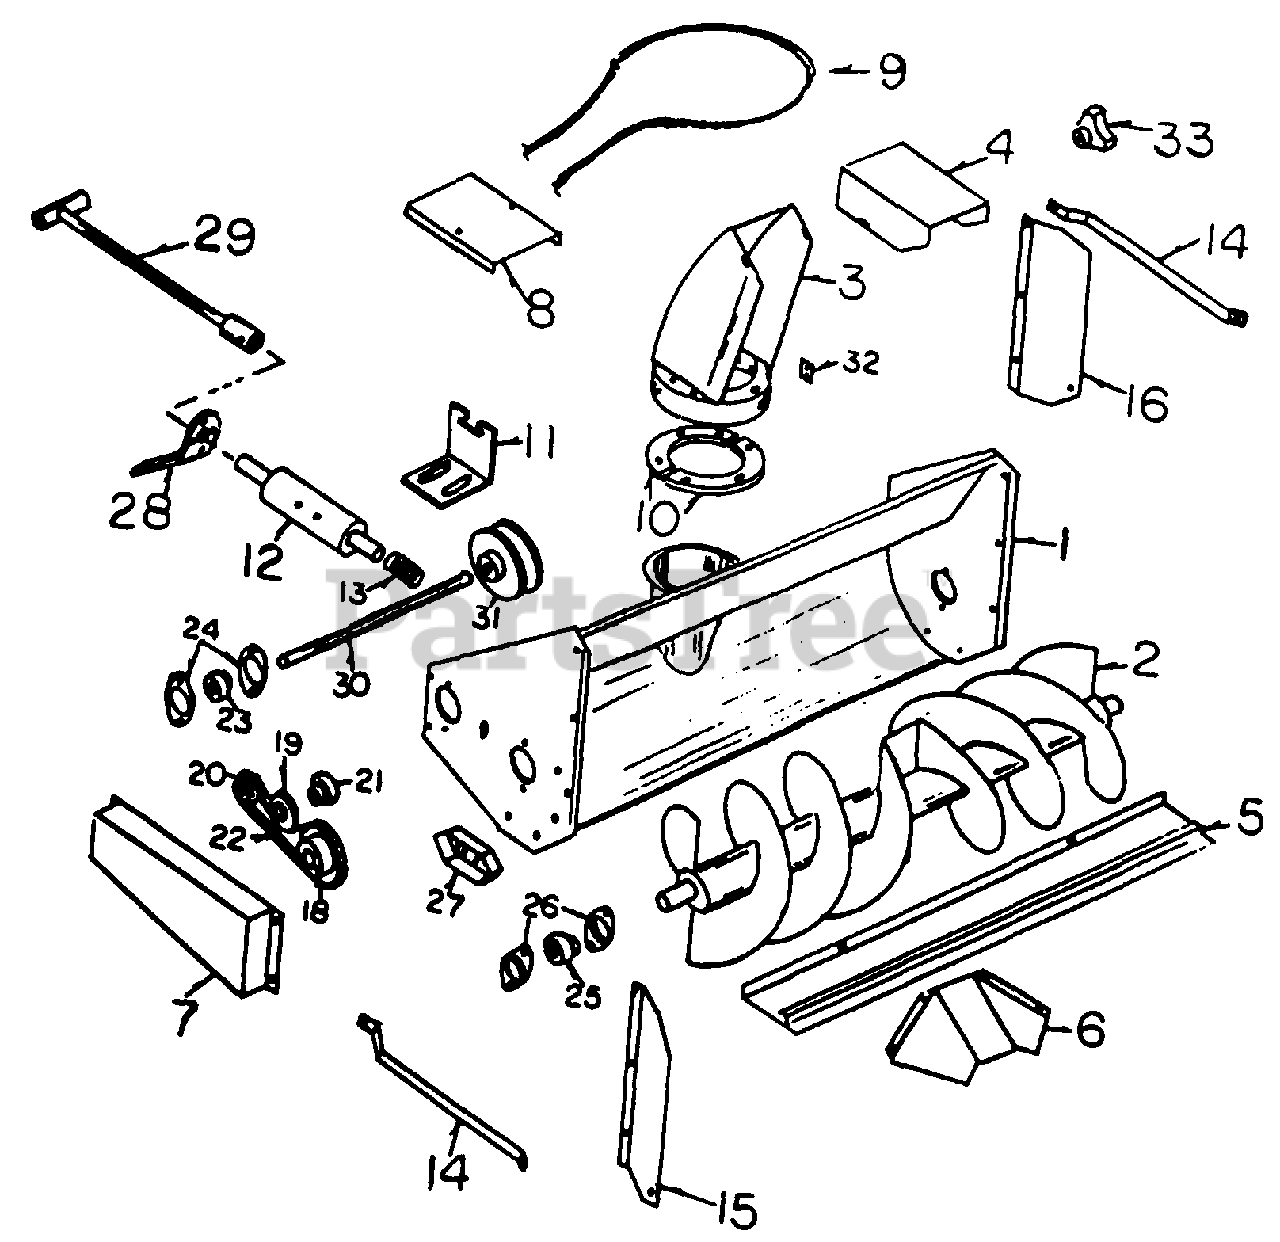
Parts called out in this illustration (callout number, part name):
1	Snow Blower Housing
2	Auger
3	Chute
4	Snow Deflector
5	Snow Blower Bit
6	Snow Retainer
7	Chain Guard
8	Belt Guard
9	Cable, 1/8" x 84"
10	Chute Clamp
11	Cable Retainer
12	Cable Pulley
13	Spring
14	Extender Brace
15	Extender, RH
16	Extender, LH
18	Auger Sprocket
19	Idler Sprocket
20	Drive Sprocket (1800)
20	Drive Sprocket (2000)
21	Idler Sprocket Bushing
22	Chain
23	Bearing, 3/4"
24	Bearing Flange, 3/4"
25	Bearing, 1"
26	Bearing Flange, 1"
27	Skid Shoe
28	Cable Pulley Support
29	Handle
30	Shaft
31	Snow Blower Pulley (1800)
31	Snow Blower Pulley (2000)
32	Cable Clamp
33	Wing Nut
